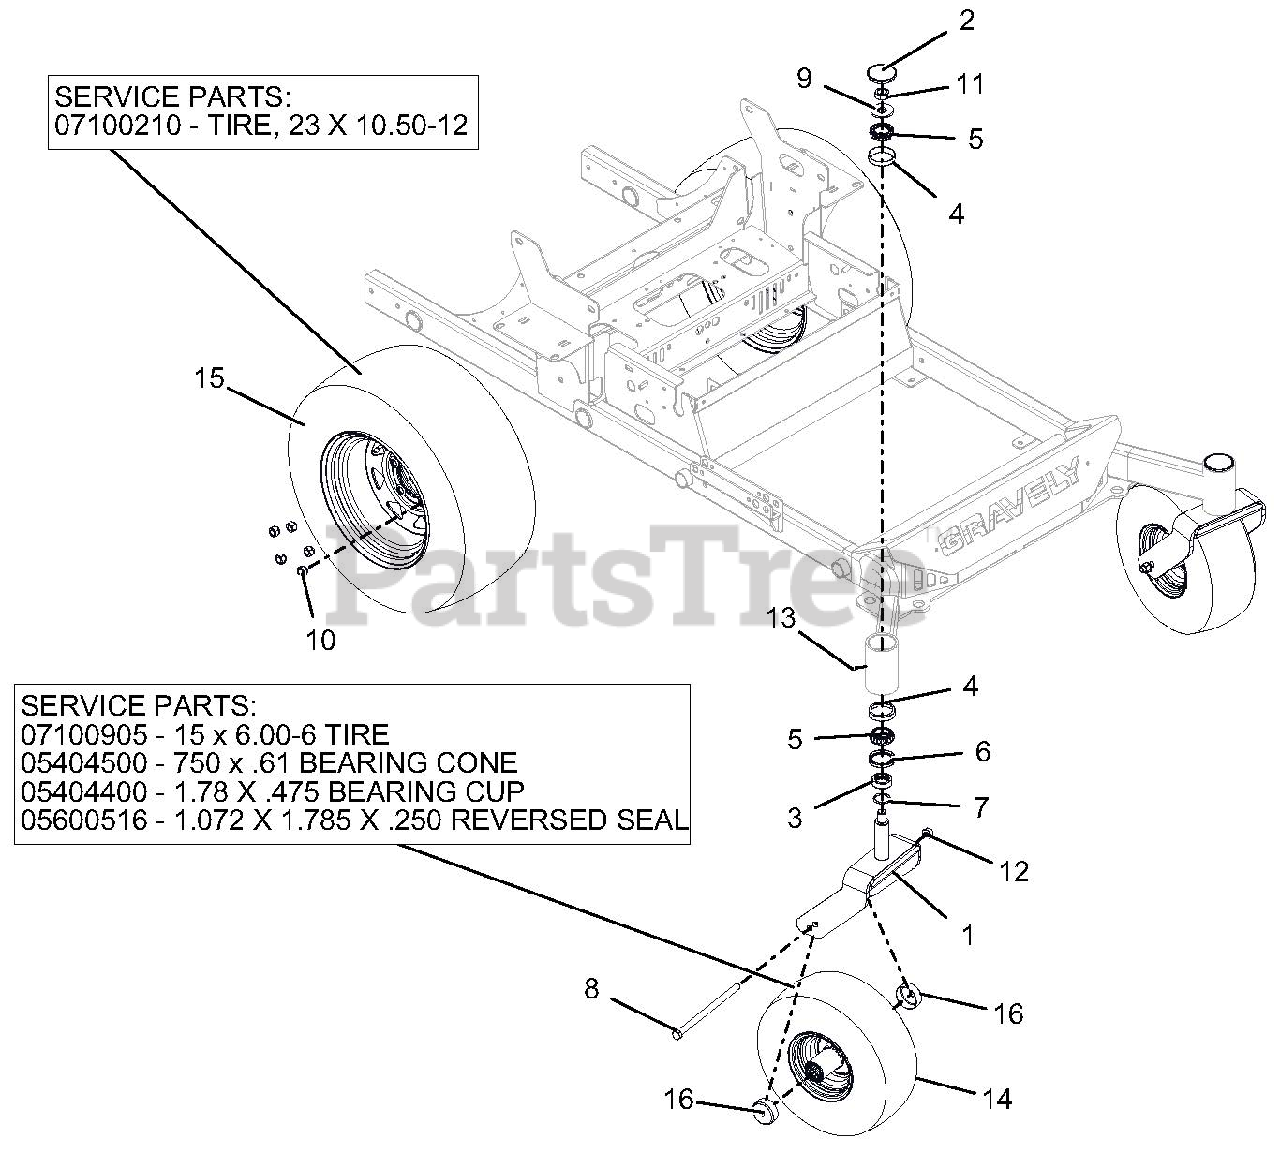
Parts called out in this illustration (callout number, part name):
1	WMT, CASTER FORK - RED
2	CAP, DUST
3	SPCR, FRONT CASTER FORK
4	BRG, CUP 2.328 X .465
5	BRG, CONE 1.250 X .660
6	SEAL, OIL 1.75 X 2.332 X .312
7	O-RING, .139 W X 1.234 ID
8	BLT-HEX .50-13X9.00 GR5 YWZC
9	WSHR-FL-STL.812X2.00X.148YWZC
10	NUT, LUG .500-13
11	NUT-LK-TOP-JAM .75-16 YWZC
12	NUT, LK-TOP-FLG .50-13 YWZC
13	FITTING, .250-28 FLUSH MOUNT GREASE
14	TIRE/WHEEL, 15 X 6.00-6 SMOOTH
14	16 X 6.00-6 TIRE
14	750 X .61 BEARING CONE
14	1.78 X .475 BEARING CUP
14	1.072 X 1.785 X .250 REVERSED SEAL
15	TIRE/WHEEL, ASM 23 x 10.5-12
15	TIRE, 23 X 10.50-12
16	SHIELD, WHEEL BEARING
